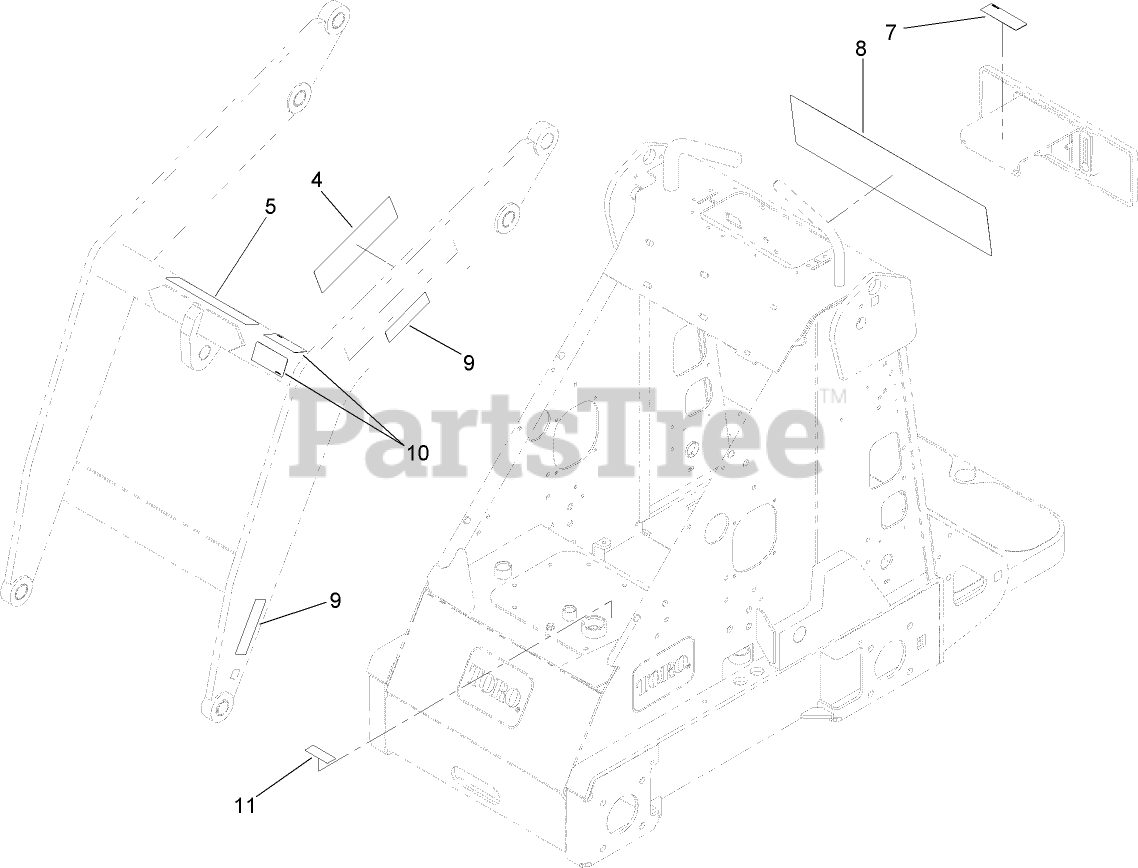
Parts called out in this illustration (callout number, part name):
4	DECAL-DANGER
5	DECAL-CAUTION
7	Decal-Information, Ce
8	DECAL-CONTROL PANEL, CE
9	DECAL-WARNING, PINCH
10	DECAL-NO RIDER
11	DECAL-OIL, HYD
